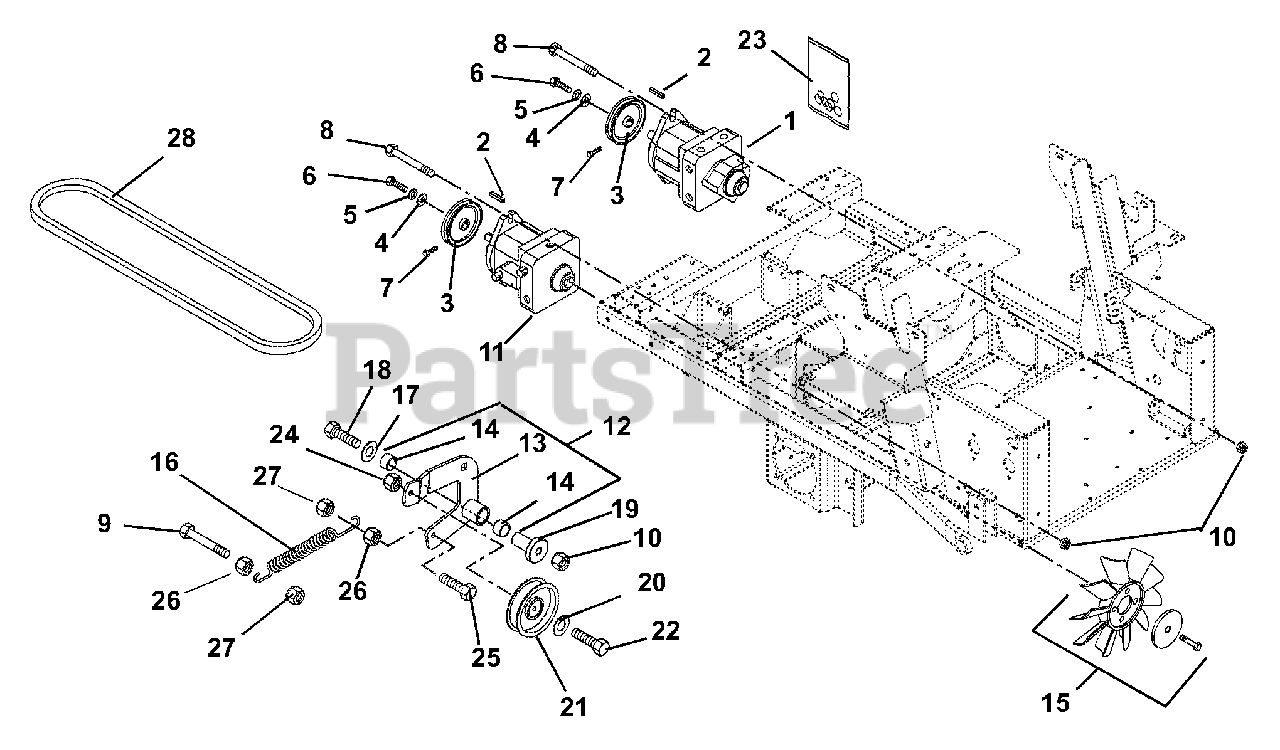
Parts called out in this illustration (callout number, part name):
1	PUMP, HYD. (RTN) W/AUX
2	KEY, SQ 5 X 5 X 30MM PLAIN
3	SHEAVE, POLY V .671 X 4.125
4	WSHR-FL-STL .281X1.000X.063
5	@WSHR-LK .25X.062 REG YWZC
6	BLT-HEX M6 X 1.0X12 YWZC
7	SCR-SKH .25-20 X .50 PH & OIL
8	@BLT-HEX .50-13X1.50 GR5 YWZC
9	@BLT-HEX .31-18X2.50 GR5 YWZC
10	@NUT-LK-TOP-FLG .50-13 YWZC
11	PUMP, HYD. (RTN)
12	ASSEMBLY, IDLER ARM
13	WMT, IDLER ARM
14	BRG, 1.00 X 1.12 X .75
15	FAN KIT, HYDROGEAR 70618
16	SG-TENS .135X.69X5.75 WLD 150
17	@WSHR-FL-STL.563X1.38X.109YWZC
18	@BLT-HEX .50-13X3.50 GR5 YWZC
19	BEARING, PEDESTAL
20	@WSHR-FL-STL.406X.812X.065 YWZ
21	IDLER, FLAT 4.00X1.06
22	BLT-HEX .38-16X1.625
23	KIT, PUMP SEAL (BDP-21L)
24	@NUT-LK-TOP-FLG .38-16 YWZC
25	@BLT-HEX .31-18X1.25 GR5 YWZC
26	@NUT-HEX .31-18 YWZC
27	@NUT-LK-TOP-FLG .31-18 YWZC
28	POLY V-BELT, K-5 RIBS
